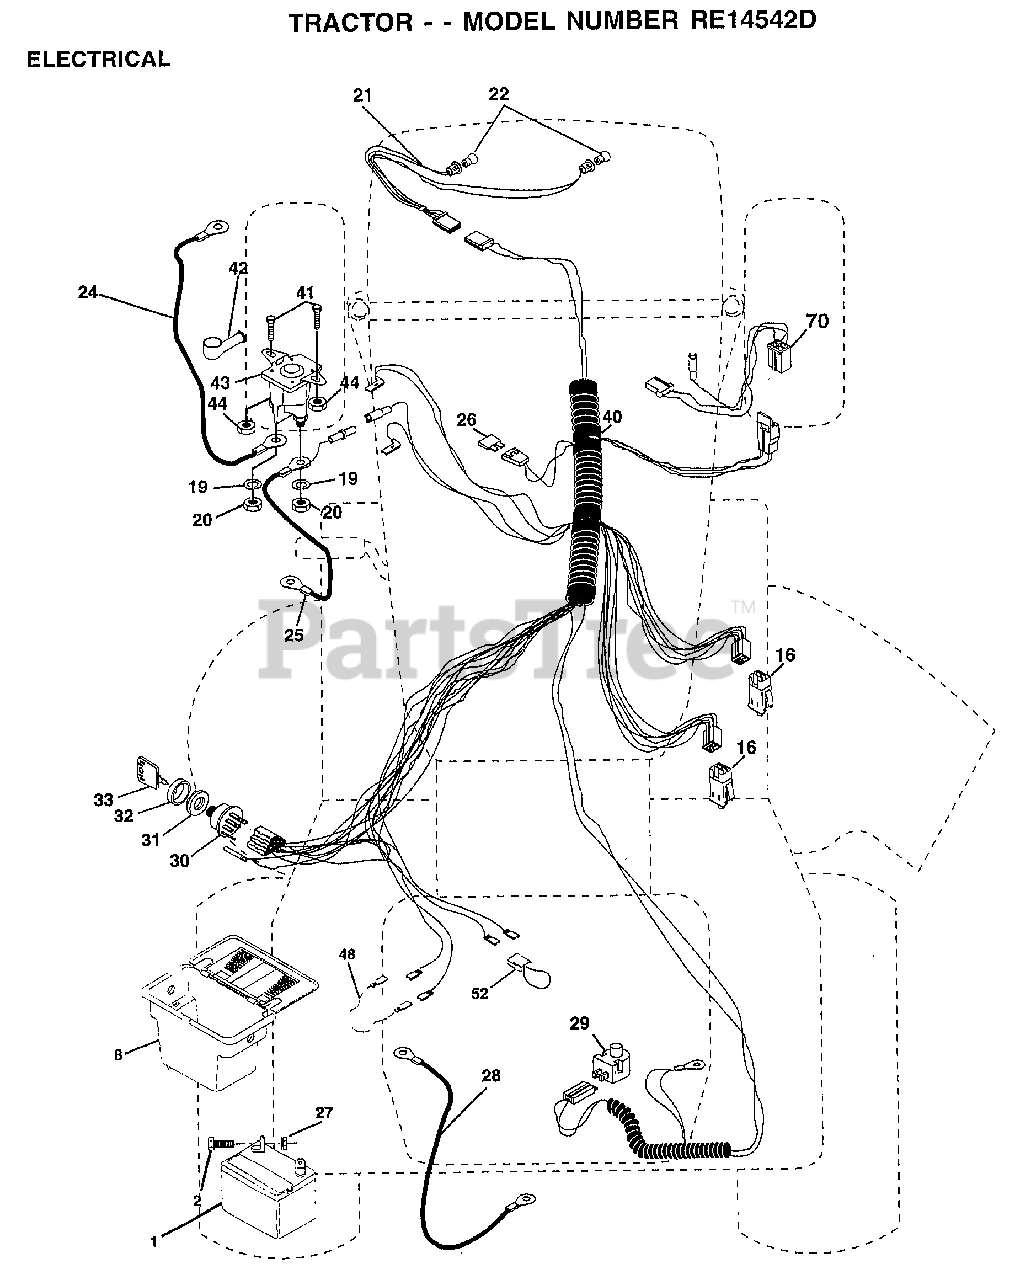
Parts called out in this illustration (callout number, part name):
2	BOLT LT
8	"CASE,BATTERY.MECH"
16	SWITCH INTERLOCK
20	NUT
21	HARNESS.ASM.LIGHT W/4152J
22	HEADLAMP BULB
24	"CABLE T, BATTERY"
25	CABLE.BTRY.6GA.RD
26	FUSE.15 AMP
27	NUT
28	CABLE T
29	SWITCH SEAT
30	SWITCH IGN 4POS
31	NUT IGNITION
32	COVER KEY SWITCH
33	KEY
40	HARNESS.IGNITION
41	BOLT HXHD FIN
44	NUT HXKEP 1/4X20
48	ADAPTER AMMETER
52	PROTECTION LOOP
70	HARNESS.ENGINE
